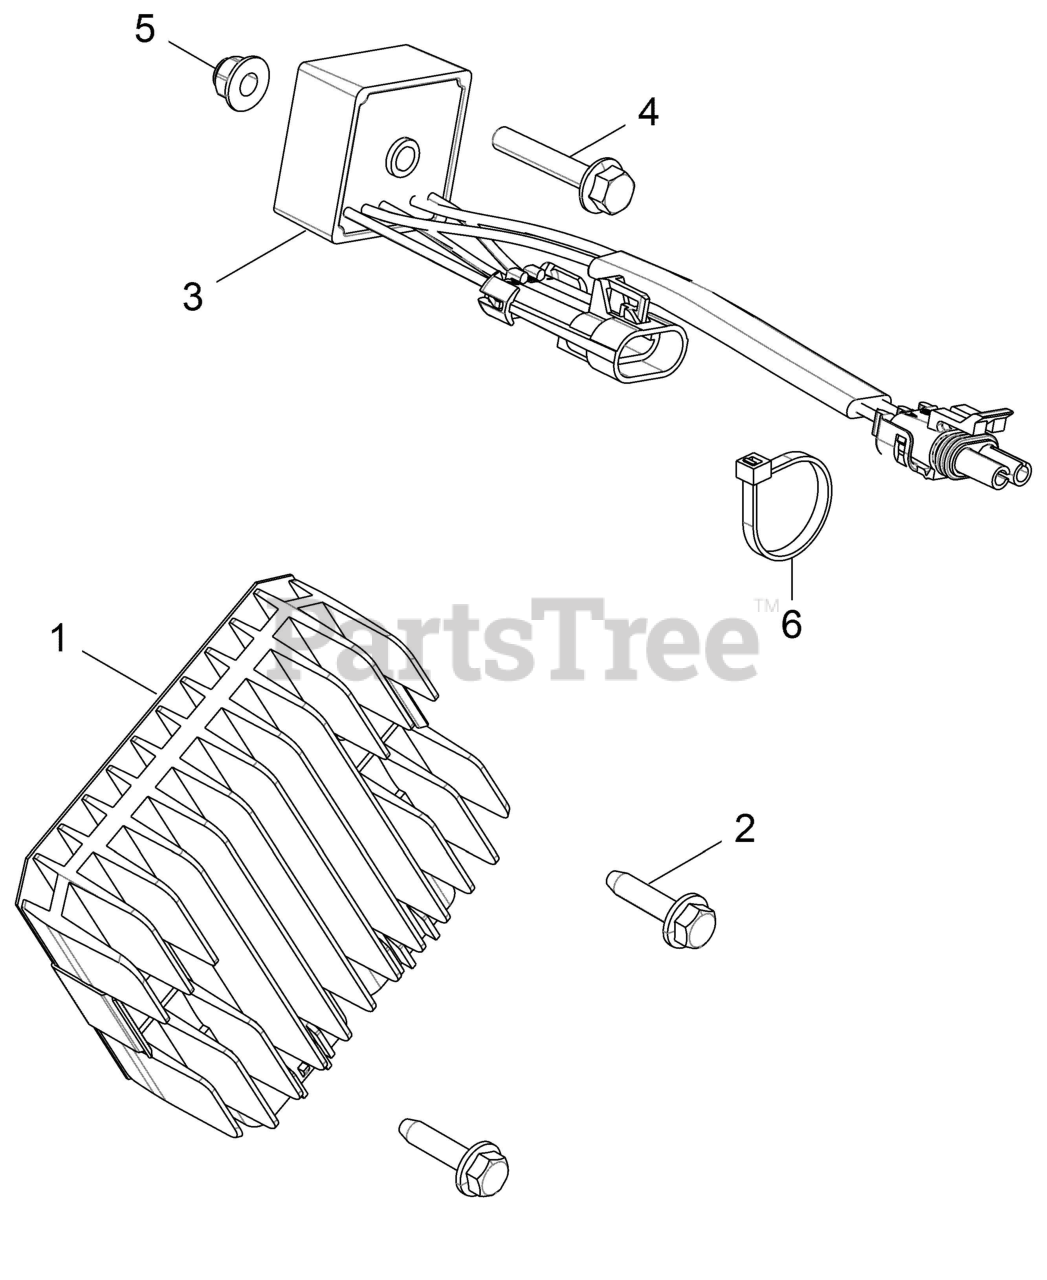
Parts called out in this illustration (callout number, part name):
1	REGULATOR-3PH,50A,SERIES,HISPD
2	SCR-TFHFL-M6X1.0X25,ZOD
3	RELAY, SOLID STATE,9A,LONG LD
4	BOLT-M6X1.0X35,HXFLG/SH-OLV D
5	NUT-M6X1.0,FLG-NYLOC-OLIVE D
6	CABLE TIE (10)
